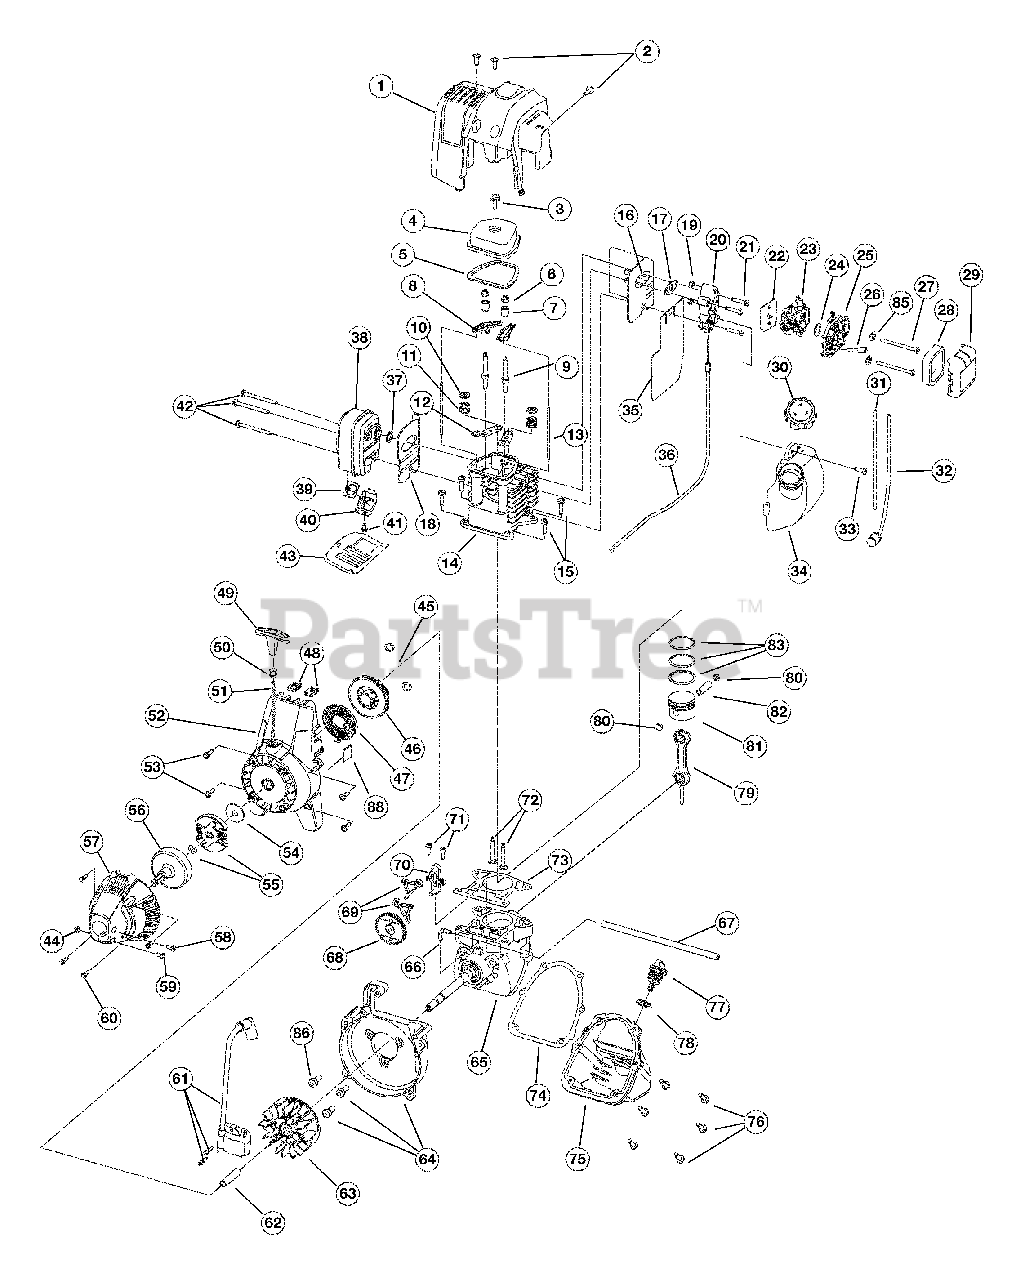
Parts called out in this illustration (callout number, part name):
1	Engine Cover
2	Engine Cover Screws
3	Valve Cover Screw
4	Valve Cover
5	Valve Cover Gasket
6	Rocker Adjustment Nut
7	Rocker Arm Pivot
8	Rocker Arm
9	Rocker Arm Stud
10	Valve Spring Retainer
11	Valve Spring
12	Push Rod Guide
13	Push Rod
14	Cylinder Assembly
15	Cylinder Screw
16	Intake Baffle
17	Carburetor Mount Gasket
18	Muffler Baffle
19	Nut
20	Carburetor Mount
21	Carburetor Mount Screw
22	Carburetor Gasket
23	Carburetor with Primer
24	O-Ring, Carburetor
25	Air Filter/Choke Cover Assembly
26	Breather Tube
27	Air Filter Mounting Screw
28	Air Filter
29	Air Filter Cover
30	Fuel Cap
31	Fuel Return Line
32	Fuel Pick-Up Line with Filter
33	Screw
34	Fuel Tank Assembly
35	Fuel Tank Shield
36	Throttle Cable
37	Muffler Gasket
38	Muffler
39	Spark Arrestor Screen
40	Screen Cover
42	Muffler Mounting Screw
43	Muffler Cover
45	Pal Nut Retaining Ring
46	Recoil Pulley
47	Recoil Spring
48	Nut Clip
49	Pull Handle
50	Rope Guide
52	Starter Housing Screw
53	Starter Housing Assembly
54	Clutch Washer
55	Clutch with Spacer
56	Clutch Drum
57	Clutch Cover
58	Anti-Rotation Screw
59	Screw
60	Clutch Cover Screw
61	Ignition Module with Screws
63	Flywheel
64	Shroud Assembly with Screws
65	Crankcase Assembly
66	90° Elbow
67	Breather Hose
68	Cam Gear
69	Cam Follower
70	Cam Bracket
71	Cam Bracket Screw
72	Valves, Intake and Exhaust
73	Cylinder Gasket
74	Oil Pan Gasket
75	Oil Pan
76	Oil Pan Screw
77	Dipstick Assembly
79	Connecting Rod
80	Wrist Pin Button
81	Piston
82	Wrist Pin
83	Piston Ring Set
86	Grommet
